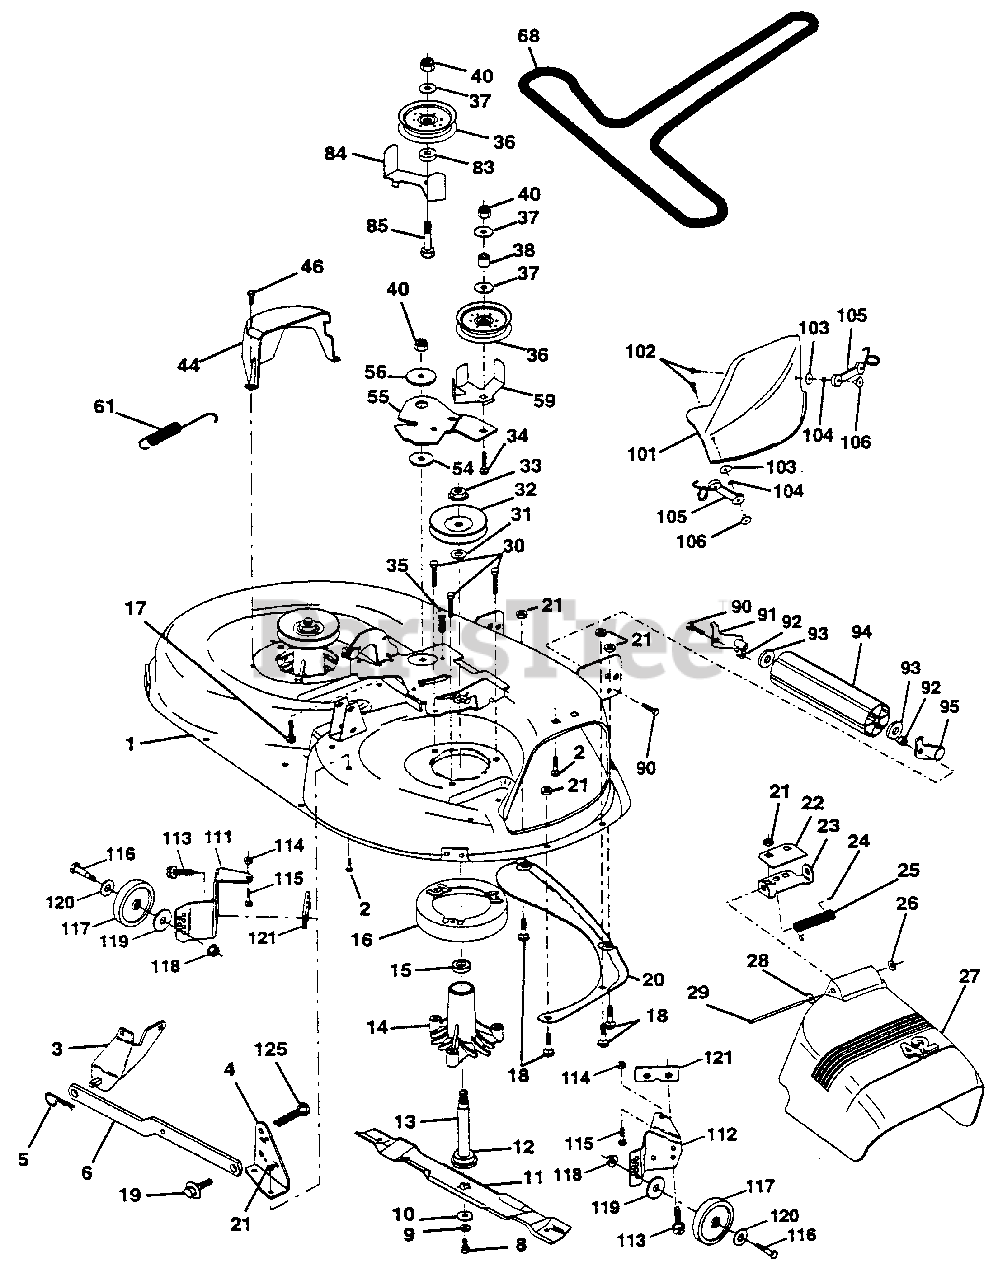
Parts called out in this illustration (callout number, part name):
1	Deck Asm MWR 42" 94 T-Path
2	Bolt Rdhd Sqnk 5/16-18unc X3/4
3	Bracket Asm Fr Sway Bar 38/42
4	Bracket Asm Deck 42" sway Bar
5	Retainer Spring
6	Arm Suspension Rear
7	Locknut-hex W/Ins 5/16-18unc P
8	Bolt 3/8-24x1 25 Gr8 Patched
9	Washer Lock Hvy 3/8 Unplated
10	Washer Hard Blade Mower Vented
11	Blade Mower Mulching 42"
12	Bearing Ball #6204 (Mandrel)
13	Shaft Asm W/lower Bearing
14	Housing Mandrel Vented (machd)
15	Bearing Ball Mandrel
16	Stripper Mower Round
17	Bolt Rdhd Sqnk 3/8-16 X 2-1/4
18	Bolt Carr 5/16-18 X 5/8
19	Bolt Shoulder
20	Baffle Vortex 42
21	Nut Crownlock 5/16-18
22	Stiffener Bracket 42" deck
23	Bracket Deflector Mower 42"
24	Cap Sleeve 80x 112 Blk Mower
25	Spring Torsion Deflector 2 52
26	Nut Push Phos & Oil
27	Shield Deflector Mower 42" Blk
28	Washer 11/32 X 5/8 X 16 Ga.
29	Rod Hinge 42" 6 75 Wlg
30	Screw Thdrol Hex Hd Zinc Mwr.
31	Washer Spacer Mower Vented
32	Pulley Mandrel 42"
33	Nut 9/16 top Lock Flng Cntr
34	Bolt Rdhd 3/8-16uncx2-3/4 Gr5
35	Fastner Christmas Tree
36	Pulley Idler Flat 3 060
37	Washer 13/32 X 13/16 X 16 Ga
38	Spacer Spring Stop Idler
40	Nut Crownlock 3/8-16 UNC
44	Guard Mandrel LH Black
46	Screw Thdrol 1/4-20x5/8
54	Washer Hardened
55	Arm Idler 42" mower LT/YT
56	Spacer Retainer Pm Mower
57	Guide, Belt
59	Guard, Belt
61	Spring Ext. Elect
68	V-Belt Mower
83	Washer Sintered
84	Keeper Belt Idler Fixed
85	Bolt RDHD SQNK 3/8-16 x 2-1/2 Gr. 5
90	Bolt Fin Hex 3/8-16unc X 1
91	Bracket Asm Noseroller LH
92	Nut Crownlock 3/8-16 Unc
93	Washer 17/32 X 7/8 X 16 Ga
94	Roller Nose 38 & 42
95	Bracket Asm Noseroller RH
101	Cover Mulching 42" Blk
102	Screw
103	Washer Lock #10
104	Washer #10
105	Latch Asm Bagger
106	Nut Weld .327/.304 #10-24
111	Bracket Wheel Gauge Lh 42" Deck
112	Bracket Gauge Wheel Rh 42" Deck
113	Screw Thdrol 5/16-18 x 3/4 M
114	Nut Keps 5/16-18 UNC
115	Bolt Carriage 5/16 - Unc x 1/2
116	Bolt Shld "A" 2.41 "B" 1.66
117	Wheel Gauge blk 4.93
118	Nut Centerlock 3/8 - 16 UNC
119	Washer 3/8 x 7/8 x 14 Ga.
120	Washer 17/32 x 15/16 x 12 Ga.
125	Pin Cotter 1/4 x 1 Plated
